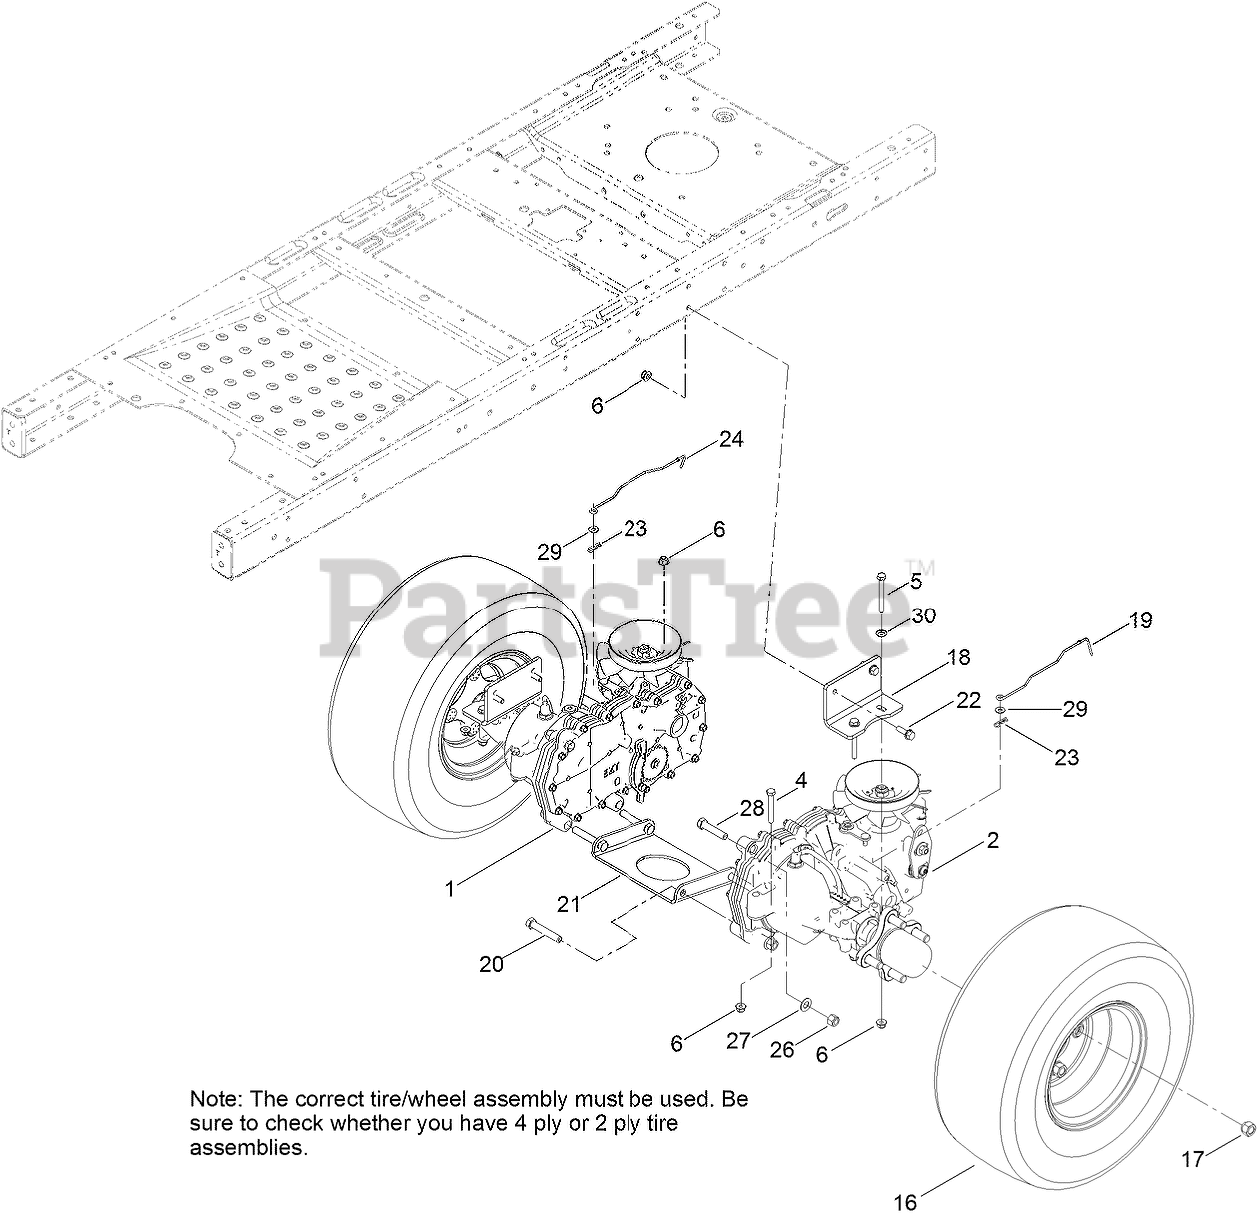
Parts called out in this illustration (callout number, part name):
1	RH HYDRO TRANSAXLE ASM
2	LH HYDRO TRANSAXLE ASM
4	SCREW-HH
5	SCREW-HH
6	NUT-HF, NI
16	4 PLY WHEEL AND TIRE ASM
16	2 PLY WHEEL AND TIRE ASM
17	NUT-LUG
18	MOUNT-HYDRO
19	ROD-BYPASS, LH
20	SCREW-HH
21	PLATE-CROSS, HYDRO
22	SCREW-HHF
23	PIN-COTTER
24	ROD-BYPASS, RH
26	NUT-LOCK, NI
27	WASHER-FLAT
28	SCREW-HH
29	WASHER
30	WASHER-PLAIN
